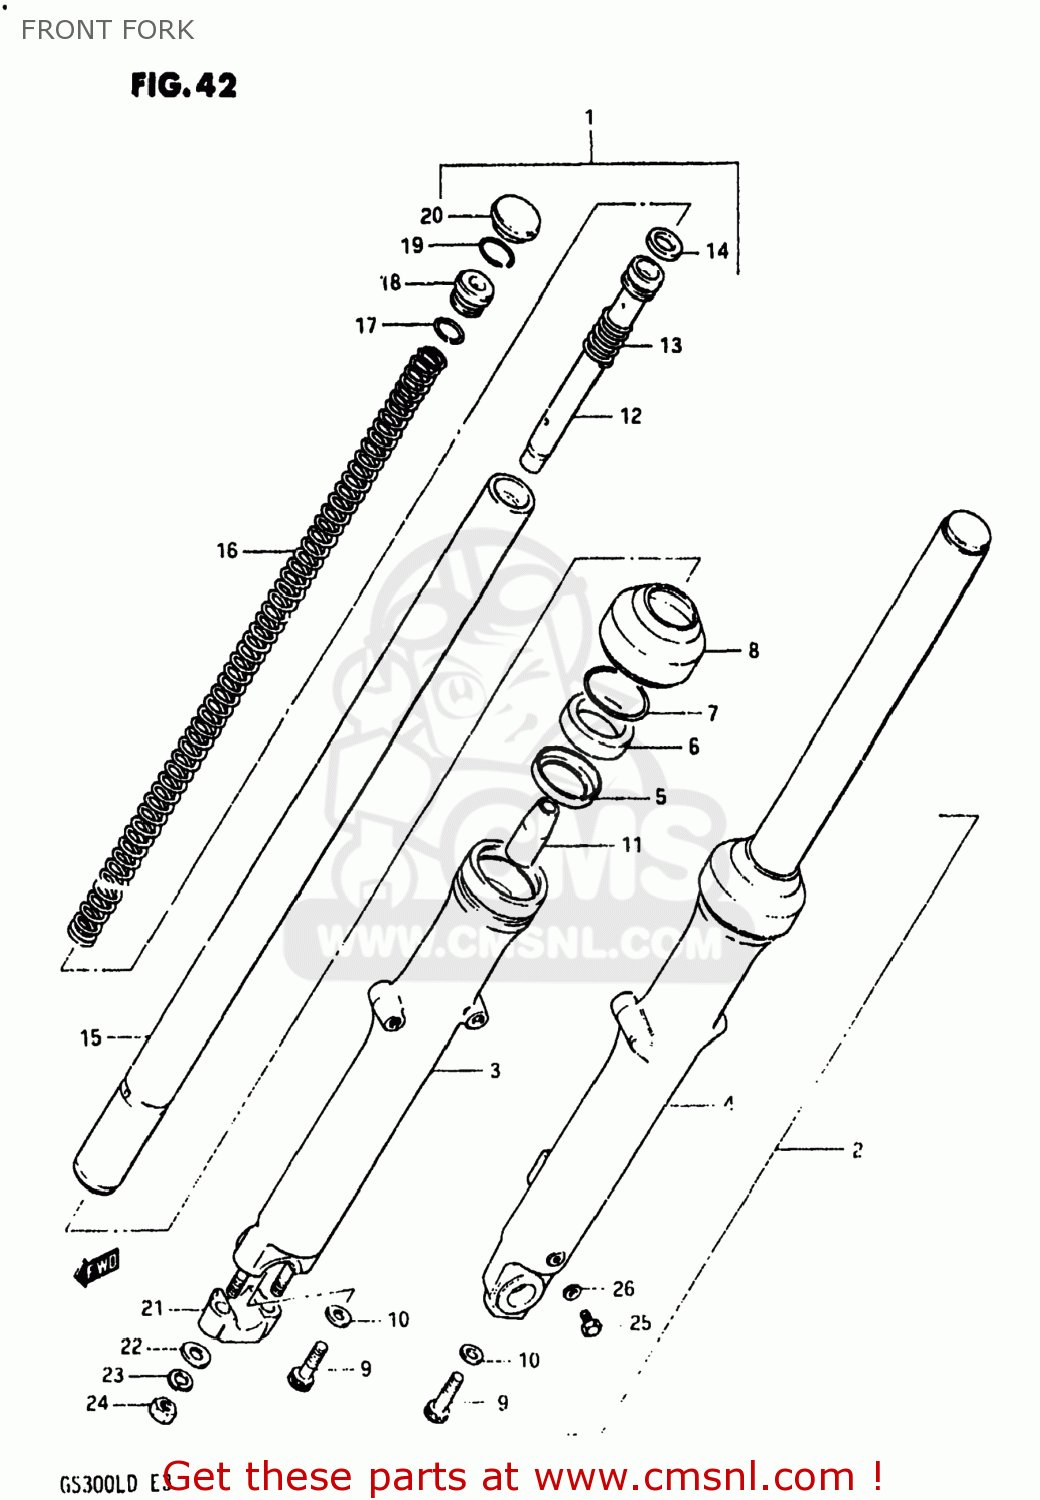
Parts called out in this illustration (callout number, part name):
1	DAMPER ASSEMBLY,FRONT FORK
2	DAMPER ASSEMBLY,FRONT FORK,LEFT
3	TUBE,OUTER,RIGHT
4	TUBE,OUTER,LEFT
5	SPACER,OIL SEAL
6	OIL SEAL,FRONT FORK
7	CIRCLIP,FORK OIL SEAL
8	DUST SEAL
9	BOLT(8X27)
10	GASKET (NAS)
11	PIECE,OIL LOCK
12	CYLINDER,FRONT FORK
13	SPRING,REBOUND
14	RING,PISTON
15	TUBE,FORK,INNER
16	SPRING,FRONT FORK
17	O RING
18	SEAT,SPRING
19	RING,STOPPER
20	CAP,FRONT FORK
21	HOLDER,AXLE
22	WASHER
23	LOCK WASHER
24	NUT
25	BOLT(6X8)
26	GASKET,DRAIN,PLUG (NAS)
